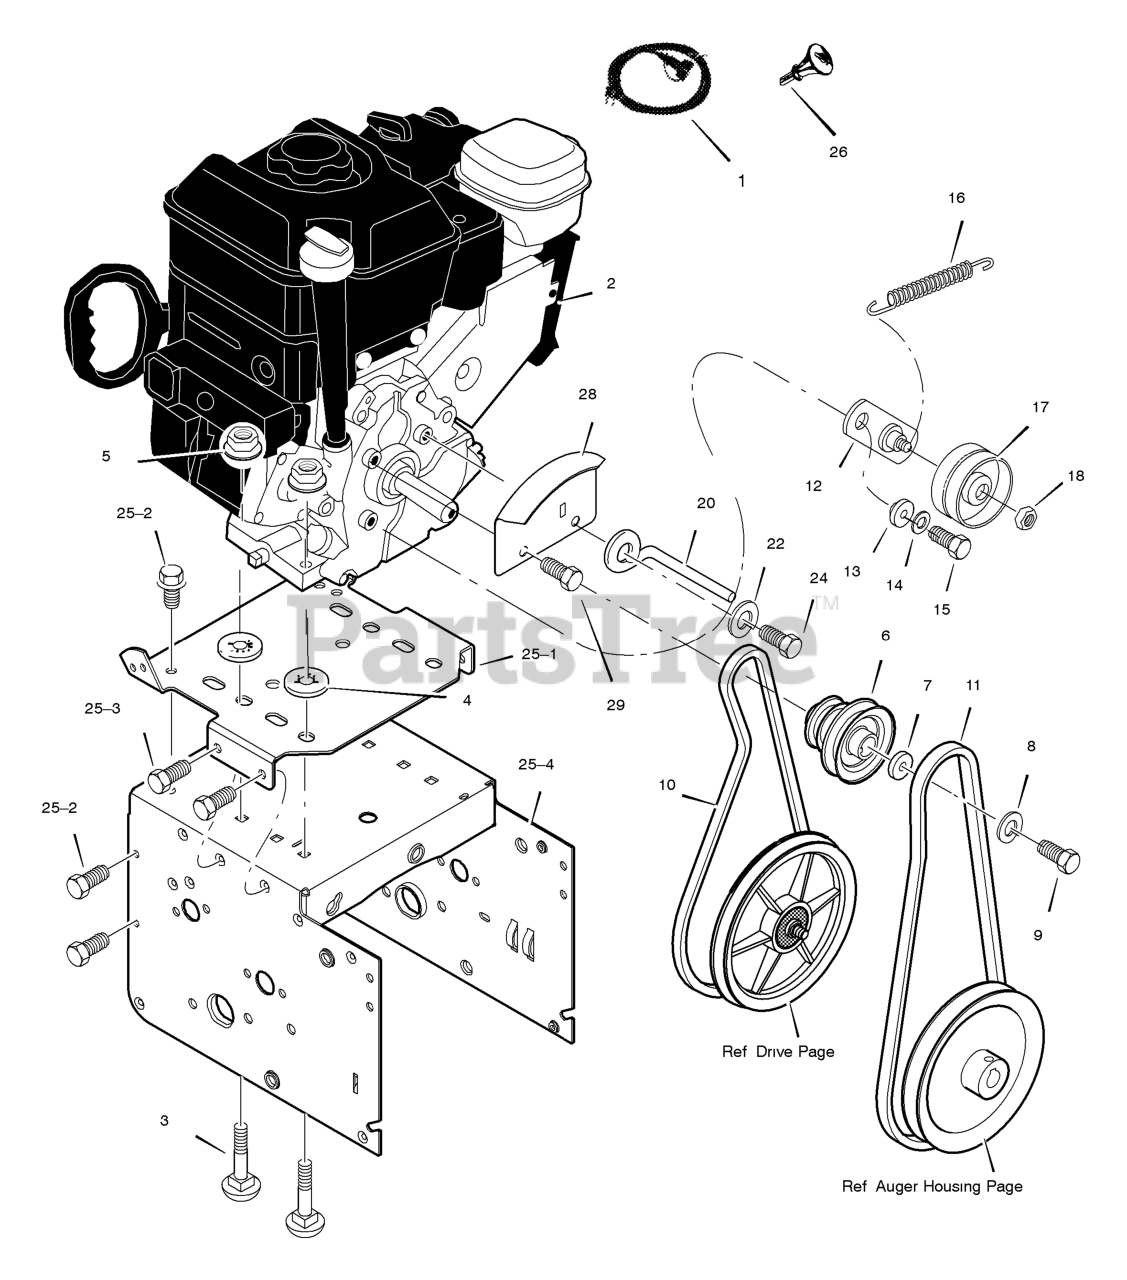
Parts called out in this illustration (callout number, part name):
1	CORD, Electric, 10FT. 110V
2	ENGINE
3	BOLT, CARRIAGE
4	RETAINER, PUSH
6	PULLEY, ENGINE
7	WASHER
8	WASHER
9	SCREW
10	BELT, DRIVE V 4L
11	BELT, AUGER V 3L
12	BRACKET ASSEMBLY, IDLER
13	BUSHING, IDLER BRACKET
14	WASHER, SPLIT
15	SCREW 5/16-24 X 0.75
16	SPRING, IDLER TRACTION DRIVE
17	PULLEY, IDLER
18	NUT, JAM 3/8-16
20	GUIDE, ROD BELT
22	WASHER
25	FRAME ASSEMBLY
25-1	PLATE, ENGINE
25-2	SCREW
25-4	MOTOR BOX
26	KEY, BRIGGS ENGINE
28	SHIELD, BRIGGS ENGINE
